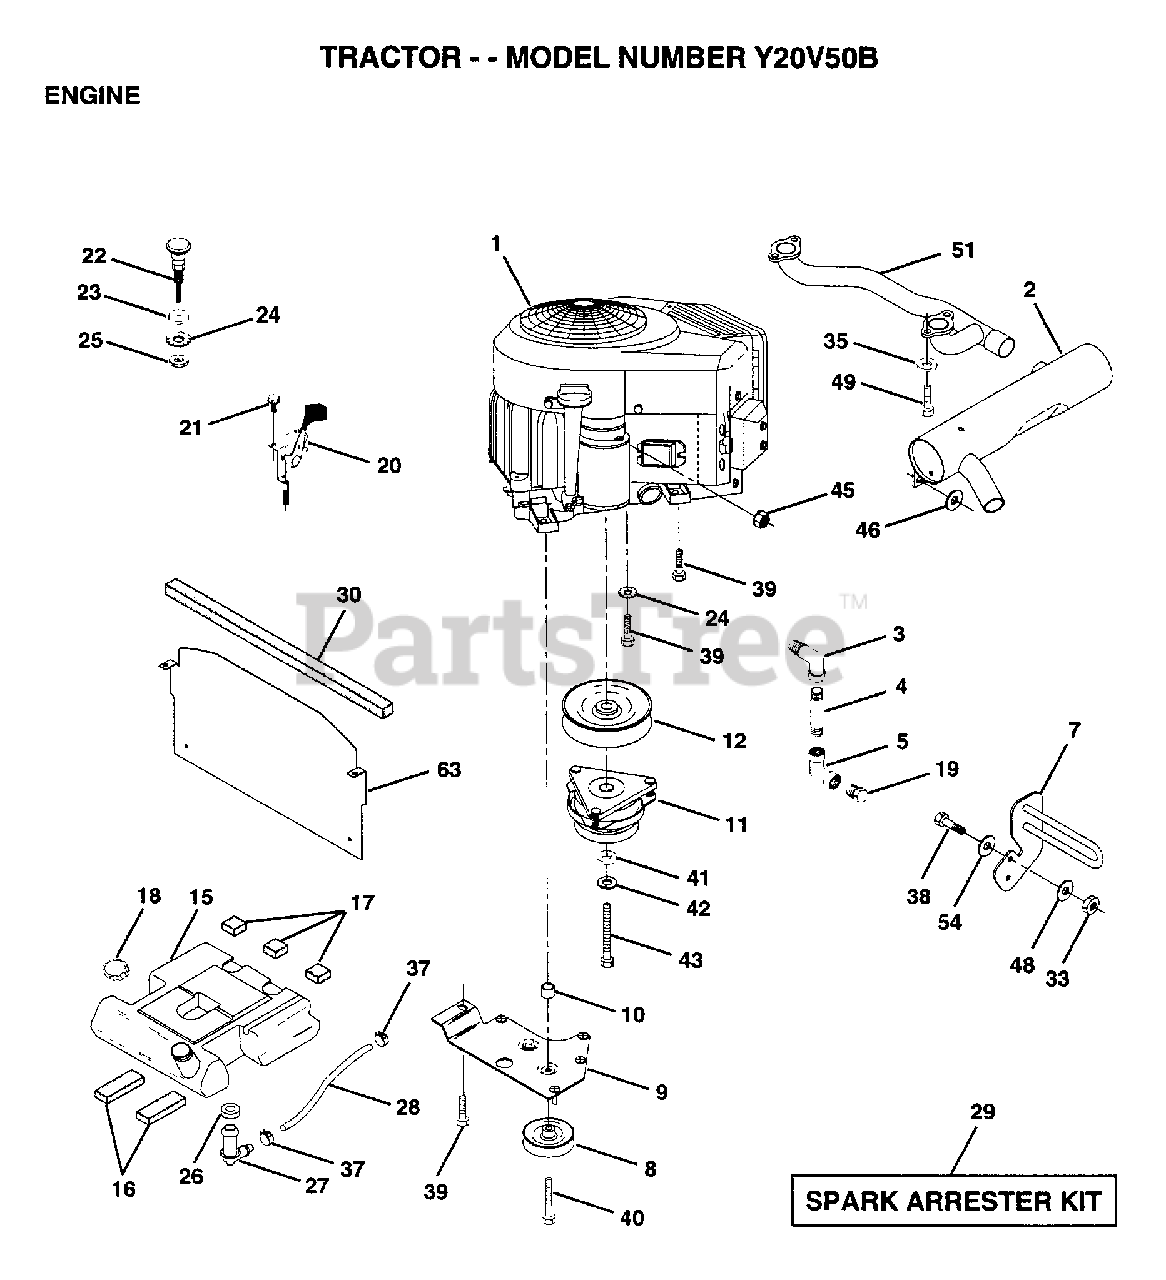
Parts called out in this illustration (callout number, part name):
3	STREET ELBOW LT
4	PIPE NIPPLE
5	ELBOW
10	BUSHING.
12	PULLEY.ENGINE.VGT
16	PAD IDLER TI
17	PAD-SPACER LT
18	CAP ASM FUEL
19	PLUG T
21	SCREW LT
23	WASHER
24	LOCKWASHER
26	BUSHING OUTLET T
27	STEM.TANK.FUEL
29	SPARK ARREST KIT
30	FOAM-STRIP LT
33	NUT
35	LOCKWASHER
37	HOSE CLAMP
38	"BOLT,HEX"
39	SCREW LT
40	SCREW.3/8-16X3.25
41	WASHER
42	LOCKWASHER
45	NUT
46	WASHER HYT
48	WASHER T
49	BOLT.HD.SOCKET.
51	PIPE.EXHAUST.B&S
54	WASHER
63	SHIELD.HEAT.VGT.
